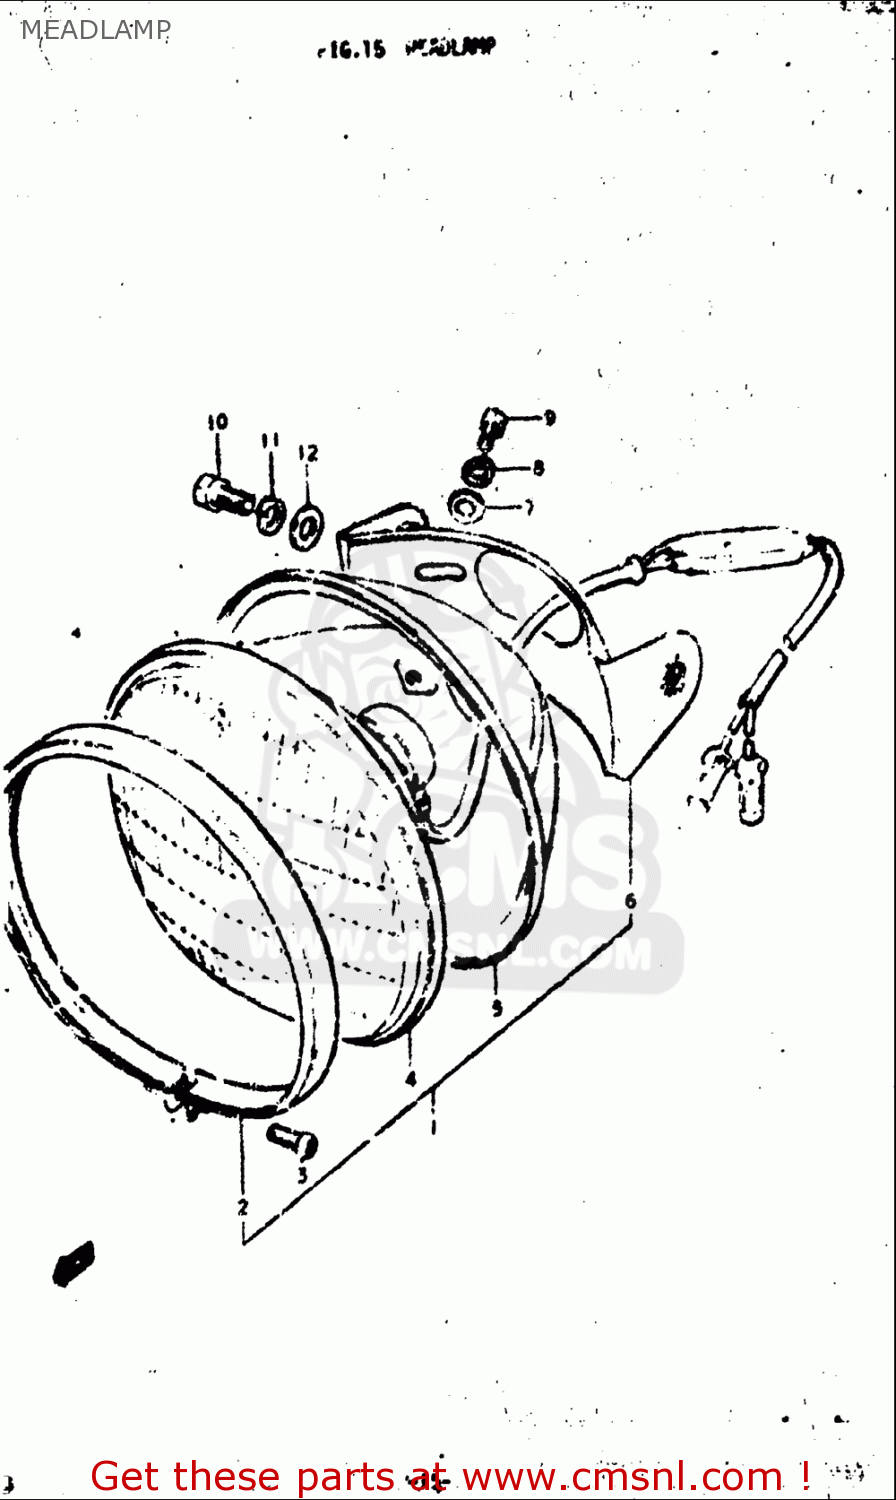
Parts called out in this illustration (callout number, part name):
3	SCREW
7	WASHER
8	WASHER,LOCK
9	BOLT
10	BOLT
11	WASHER,LOCK
12	WASHER (10.5X22X2.3)
